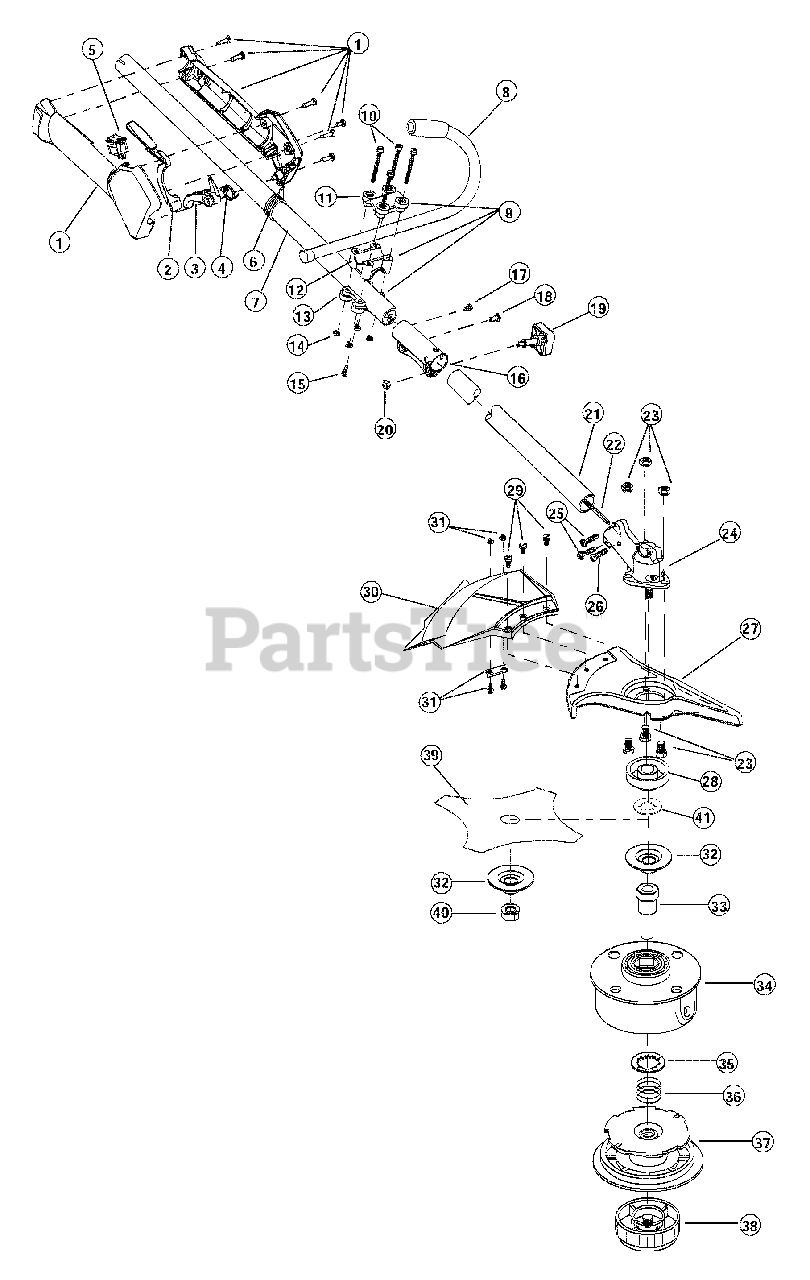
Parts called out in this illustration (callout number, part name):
1	Throttle Housing and Trigger Assembly
2	Throttle Trigger Lock-Out
3	Throttle Trigger
4	Throttle Trigger Spring
5	Switch Assembly
6	Harness Clip
7	Upper Drive Shaft Housing Assembly
8	J-Handle Assembly
9	Handle Bracket Assembly
11	Upper Handle Clamp
12	Middle Handle Clamp
13	Lower Handle Clamp
15	Anti-Rotation Screw
16	Split Boom Coupler
19	Adjustment Knob
20	Knob Retaining Nut
21	Lower Drive Shaft Housing Assembly
22	Lower Flexible Drive Shaft
23	Shield Mount Screw Assembly
24	2 piece Gearbox Assembly
25	Gearbox Screw
26	Anti-Rotation Screw
27	Blade Shield/Shield Mount
28	Blade Driver
29	Shield Mounting Screw
30	Shield and Blade Assembly
31	Blade Assembly
32	Retaining Washer
33	Spool Shaft
34	Outer Spool and Eyelet Assembly
35	Retainer
38	Bump Head Knob Assembly
39	4-Tooth Blade
40	Nut
